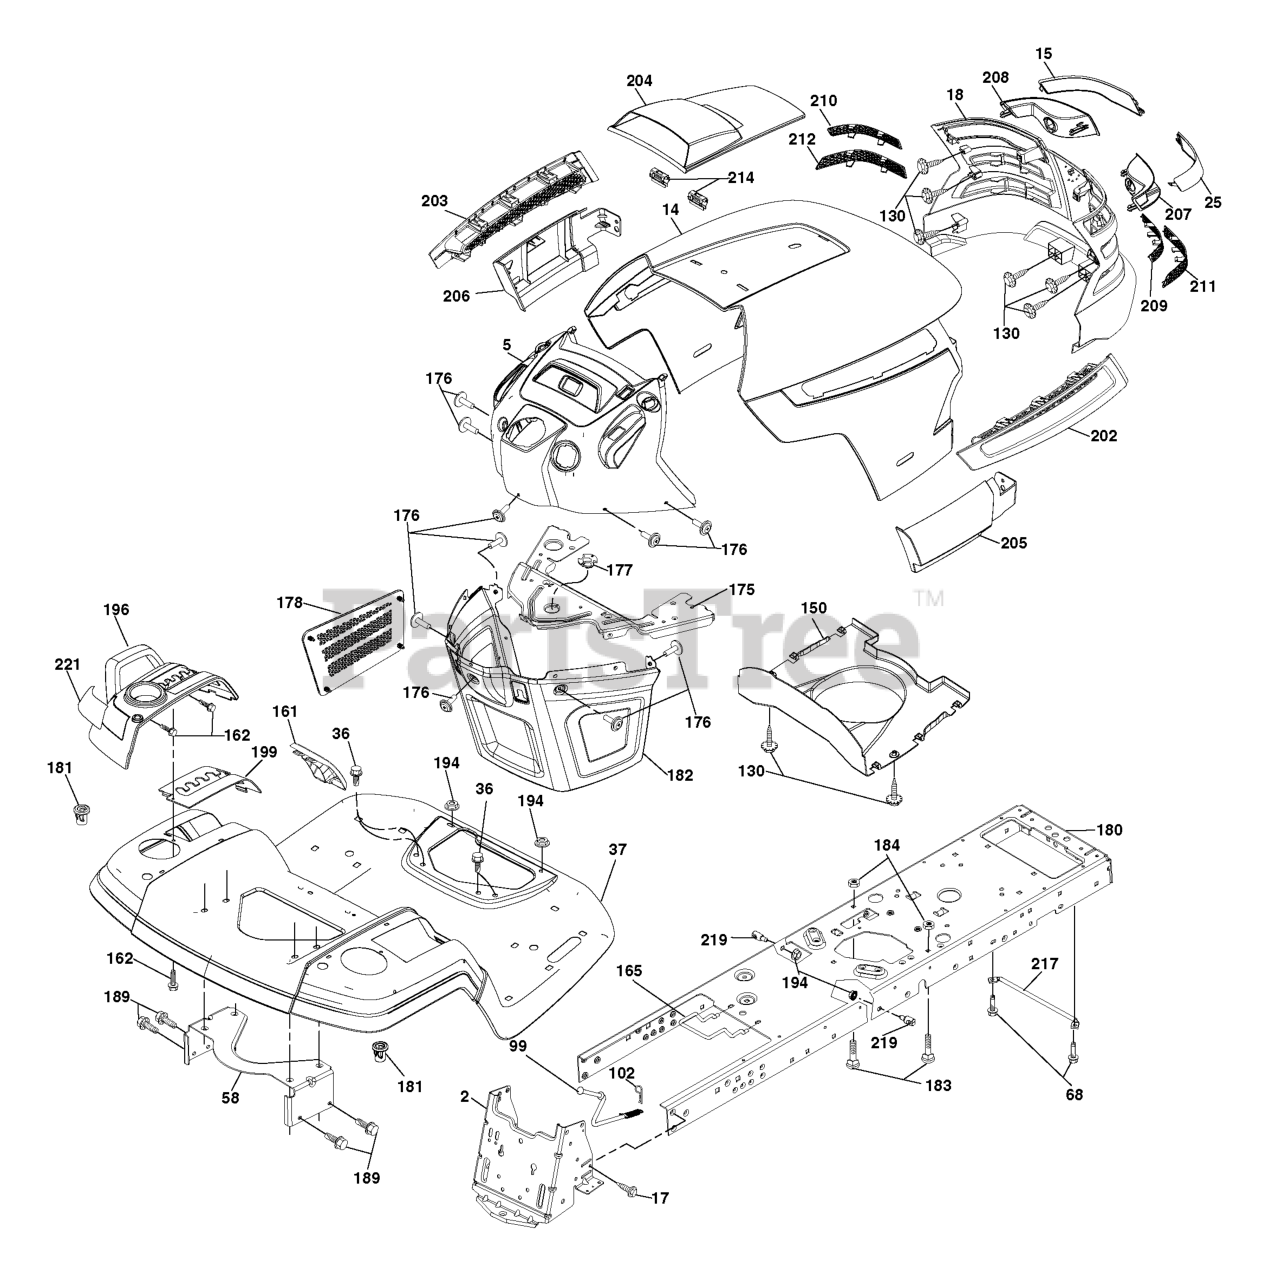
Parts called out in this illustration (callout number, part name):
2	DRAWBAR.TGB/TGW
5	DASH.HUSQ.UPR.ELE.SVMD
14	HOOD.PNT.HUSQVARNA.GT.
15	LENS.LH.TEX.GT.HUSQ.CL
17	SCREW 3/8-16X3/4
18	GRILLE.ASM.TX.GT.HUSQ
25	LENS.RH.TEX.GT.HUSQ.CL
36	SCREW 5/16"
37	FENDER.PNT.TX.GT.CH/FW.ORANGE
58	BRKT.SUPPORT.FNDR/TANK
68	Screw 5/16-18 x 1/2
99	ROD.BYPASS.K46.TG
102	RETAINER M
130	SCREW
150	AIR.DUCT.TEXGT.HUSQ.SV
161	CONSOLE.FUEL.WINDOW.HU
162	SCREW.HI-LO.CONSOLE
165	SUPPORT.TANK.REAR.B/TE
175	PLATE.CROSSMEMBER.HUSQ
176	SCREW.#10-24X5/8.RN.QU
177	BUSHING, STEERING
178	CARGO.ASM.NET.TXGT.W/C
180	CHASSIS.STAMPING.LT/GT
181	BUSHING.MNT.FEND.CRGO.
182	DASH.LOWER.COMMON.12V.
183	BOLT.5/16-18X1-1/4 FULL.THREAD
184	SPACER.FENDER
194	NUT LOCK HEX FLANGE 5/16-18
195	PLUG.HOLE.DASH.LOWER.12V.BLK
196	RP CONSOLE.ASM.DECKLFT.W/
199	PLATE.DECK.LIFT.HUSQVARNA.GT
202	VENT.SIDE.HOOD.HUSQ.RH.GREY
203	VENT.SIDE.HOOD.HUSQ.LH.GRAY
204	VENT.TOP.HOOD.HUSQVARN
205	SKIRT.HOOD.SIDE.HUSQ.RH.GREY
206	SKIRT.HOOD.SIDE.HUSQ.LH.GREY
207	BEZEL.RH.TEX.GT.HUSQ
208	BEZEL.LH.TEX.GT.HUSQ
209	INSERT.HEX.GRILL.HUSQ.GREY
210	INSERT.HEX.GRILL.HUSQ.
211	INSERT.HEX.GRILL.HUSQ.
212	INSERT.HEX.GRILL.HUSQ.
214	CLIP.RETAINER.TINNER.
217	ROD PIVOT CHASSIS/HOOD
219	STUD.FASTNER.W/ANTI-ROTATE
221	REFLECTOR.LH.TEX GT HU
